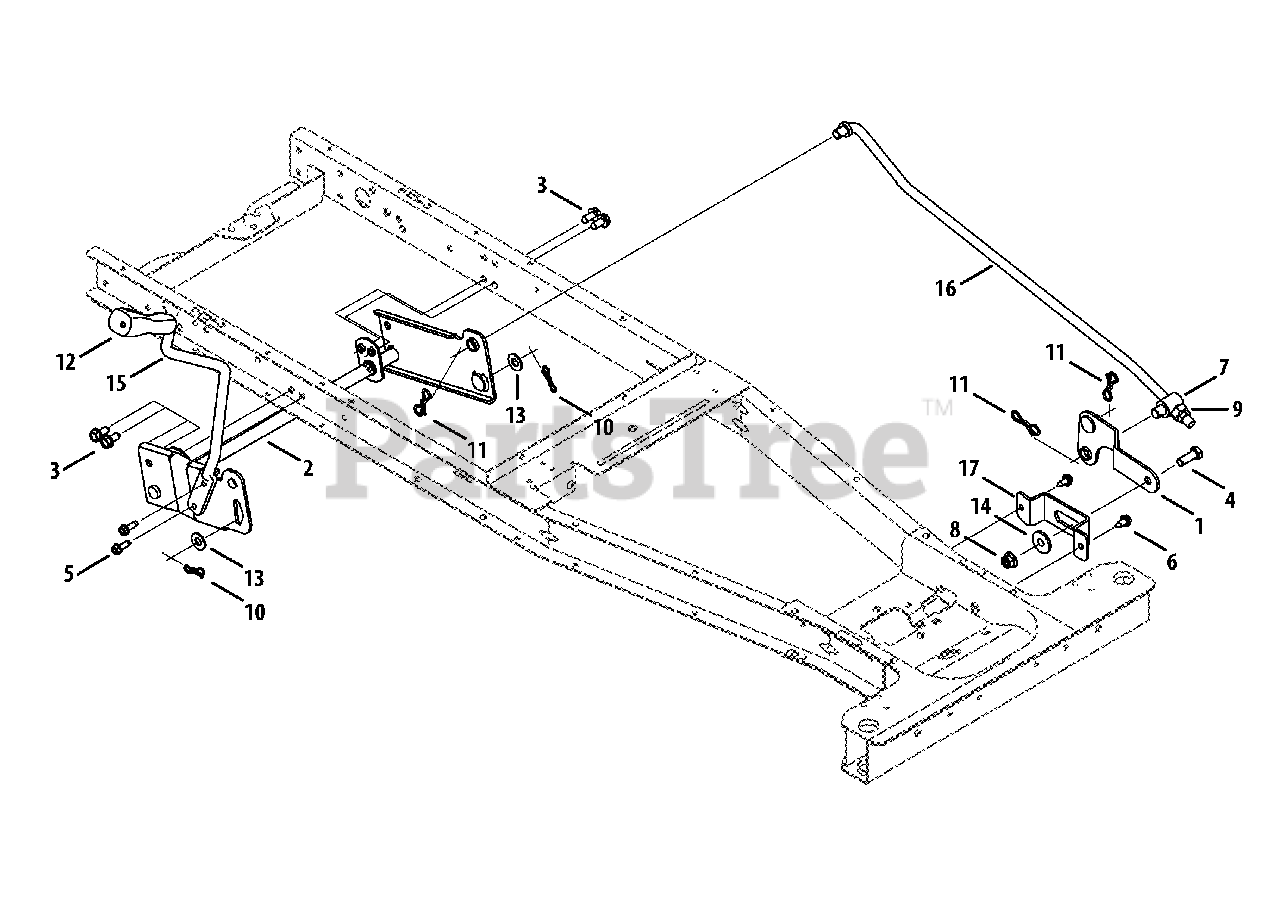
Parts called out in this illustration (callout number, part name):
1	Front Hanger Bracket Assembly
2	Lift Assembly Shaft
3	Tap Screw, 5/16-18, .750
4	Hex Head Screw, 3/8-16, 1.00
5	Tap Screw, 1/4-20, 0.750
6	Tap Screw, 1/4-20 X .625
7	Ferrule, .50 X .50
8	Flange Lock Nut, 3/8-16
9	Flex Lock Nut, 1/2-13
10	Bow-Tie Cotter Pin, 72
11	Bow-Tie Cotter Pin, 91
12	Grip Handle, 1/2
13	Flat Washer, .406 X .875 X .059
14	Shoulder Spacer, .625 ID X .169
15	Deck Lift Rod
16	Lift Link Rod
17	Front Deck Mounting Bracket
